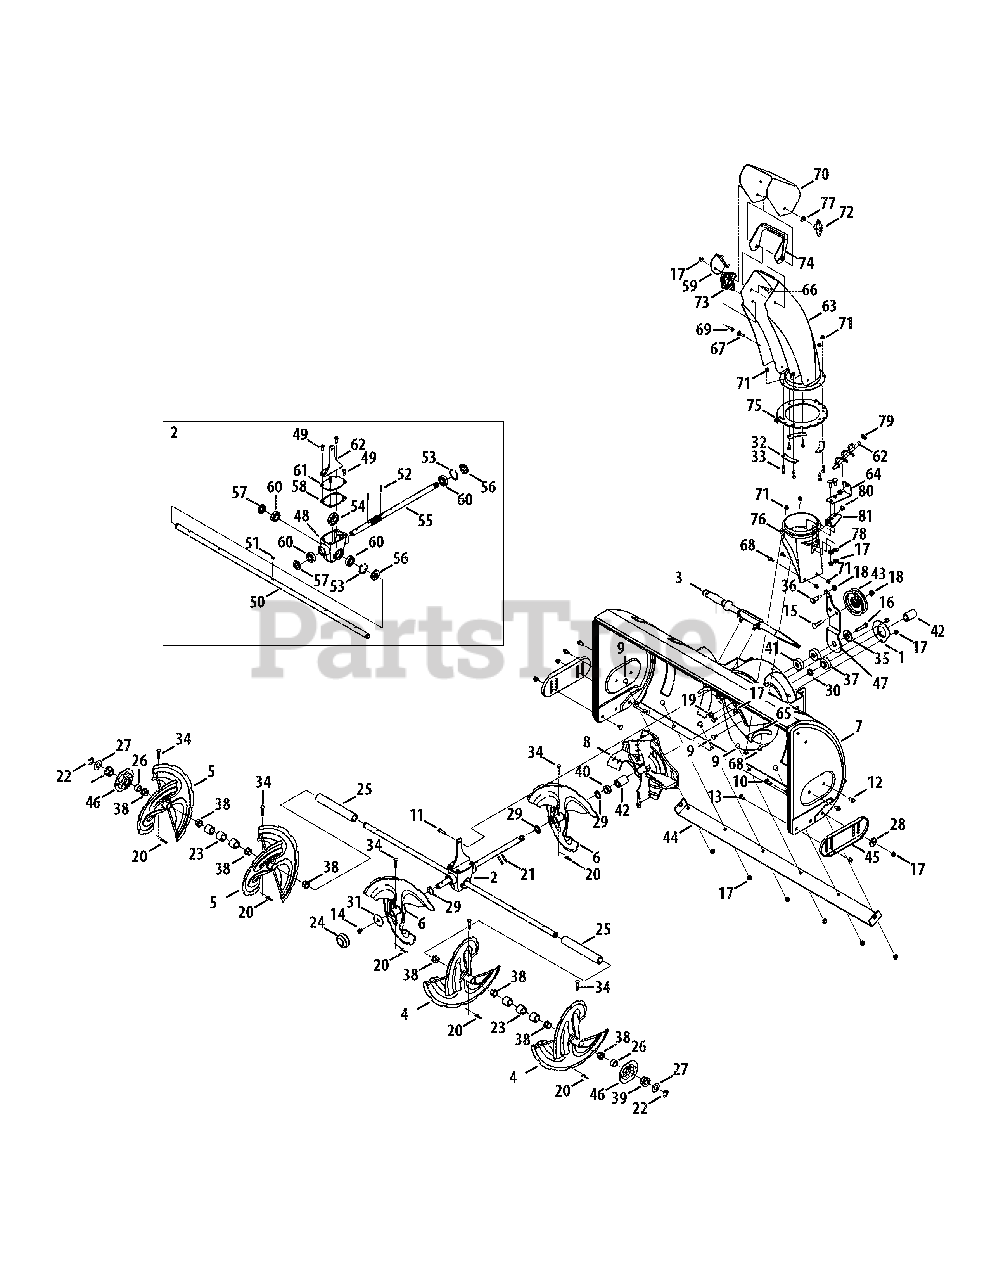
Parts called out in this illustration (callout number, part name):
1	Housing, Bearing, 1.85 ID
2	Gearbox Assembly, Auger, 42"
3	Cleanout Tool Mount
3	Cleanout Tool
4	Spiral Assembly, LH
5	Sipral Assembly, RH
6	Accelerator Assembly
7	Housing, Auger, 42" w/ Baffl e
8	Impeller Assembly, 12" Dia
9	Bolt, Carriage, 5/16-18, .62, Gr5
10	Screw, Carriage, 5/16-18, 1.00
11	Hex Screw, 5/16-18, 1.00, Gr5, Std
12	Screw, Self-tapping, 5/16-18, .750
13	Bolt, Carriage, 5/16-18, .750
14	Screw, Self-tapping, 5/16-18, .500
15	Screw, Carriage, 3/8-16, 1.75, Gr5
16	Hex Screw, 3/8-16, 2.00, Gr5, Std
17	Nut, Flange Lock, 5/16-18, Nylon
18	Nut, Flange Lock, 3/8-16, Grf, Nylon
19	Nut, Flange Lock, 3/8-16, Grf
20	Pin, Cotter, bow-Tie
21	Spring, Pin, .250 Dia x 1.50 Spiral
22	Ring, E Type, .750
23	Spacer, 1.25Od x .75Id x 1.00 Lg
25	Spacer, 1.25 OD x .75 ID x 7.805 Lg
26	Sleeve, .758 X 1.00 x .555
27	Washer, Flat, .76 x 1.49 x .06, Ht
28	Washer, Flat, .344 x 1.125 x .12
29	Washer, Flat, .793 x 1.24 x .06, Ht
30	Washer, Flat, .75 x 1.13 x .10
31	Washer, Flat, .406 x 1.92 x .060
32	Chute, Flange Keeper
33	Hex Screw, 1/4-20, 1.00,
34	Pin, Shear, .25X1.50, Gr2
35	Spacer, Shoulder, .8840 x .190
36	Screw, Shoulder, .5 x .875 x 3/18-16
37	Bearing, Ball, .75 ID x 1.85 OD
38	Bush, Flange, .800 ID x .910 OD
39	Bearing, Hex Flange x .75 ID
40	Spacer, .766 ID x 1.25 OD x .415
41	Spacer, .385Id x 1.75 OD x .585
42	Spacer, .76Id x 1.25 OD x 1.81 Lg
43	Pulley, Idler, 3.50 Dia.
44	Bracket, Skid Plate, 42"
46	Housing, Bearing, 1.1605" Hex
47	Bracket, Idler, Pivot
48	Housing, Auger, 500
49	Screw, Self-tapping, 1/4-20, 0.75
50	Axle, Auger, .75 OD x 41.62 Lg
51	Key, Hi-Pro 3/16 x 5/8
52	Pin, Roll, .25 x 1.00
53	Ring, Retaining
54	Gear, Worm, 20T
55	Shaft, Worm .75 OD
56	Seal, .75 x 40Mm x .25
57	Seal, .75 x 1.375 x .25
58	Gskt, Cover, Gearbox
59	Bracket, Cable
60	Bearing, Ball, .750X40x12
61	Cover, Gearbox, 500
62	Bracket, Support, Gearbox
63	Chute Assembly, Steel 5.0"
64	Bracket, Chute, Crank
65	Reinforcment, Chute, 5.0
66	Bolt, Carriage, 5/16-18, 1.50, Gr2
67	Screw, Carriage, Spl, 5/16-18, 1.00
68	Screw, Carriage, 1/4-20, .75, Gr5
69	Screw, 1/4-15, 0.750, Hxindwsh
71	Nut, Flange Lock, 1/4-20, Grf, Nylon
72	Knob Assembly, Wing Nut 5/16-18
73	Guide, Cable, Chute Tilt 1.05"
74	Adapter, Chute, Upper
75	Ring, Chute, 5"
76	Chute, Adapter 5" Dia
77	Washer, Flat, .349X.879X.063
78	Washer, Bell, .340 x .872 x .060
79	Washer, Flat, .406 x .875 x .059
80	Bearing, Flange, Snap .385 ID
81	Bracket, Chute Crank
